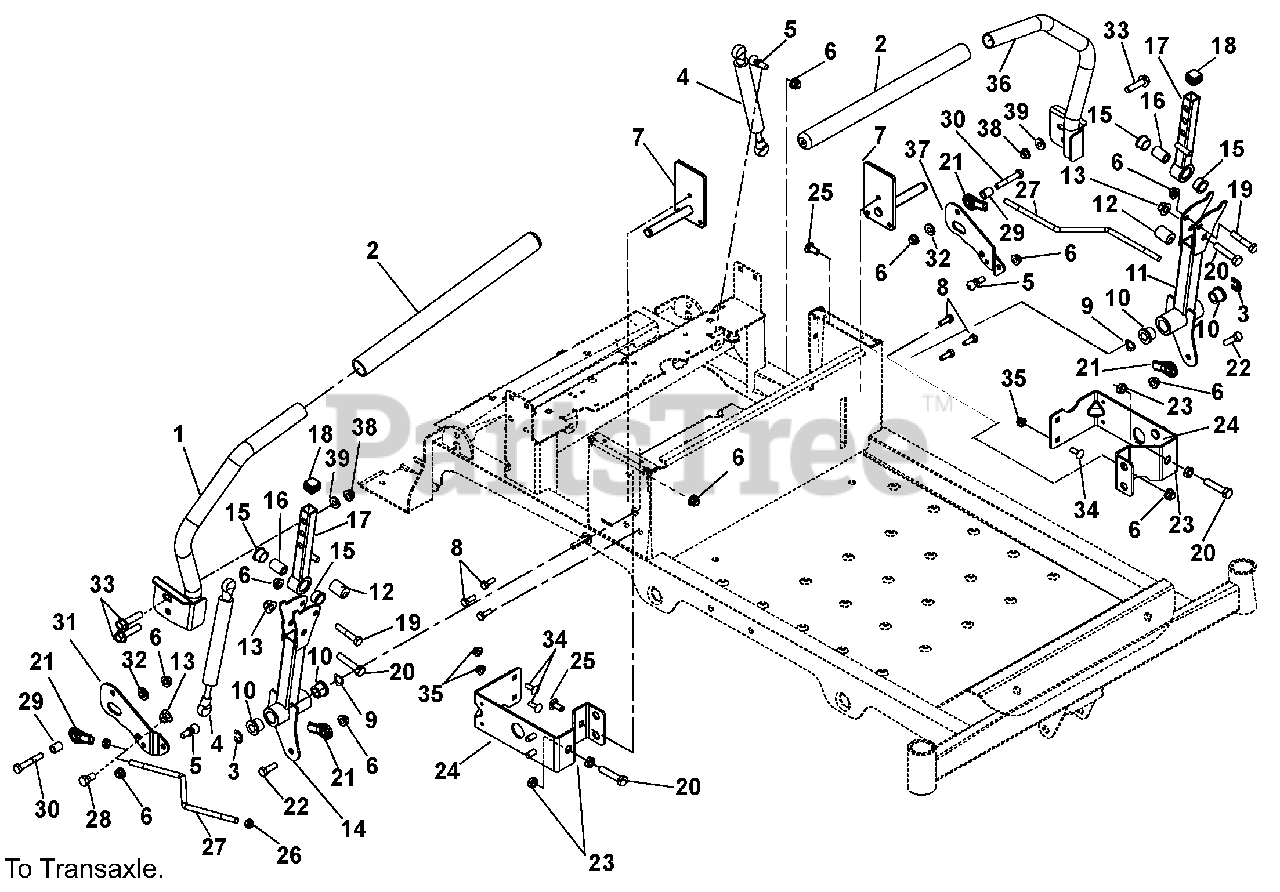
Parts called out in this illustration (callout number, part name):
1	Weldment, Steering Handle Right Hand
2	Grip, Handlebar 15" Foam
3	Ring, Retaining External .438 x 1.00 x 0.83
5	Stud, Ball
6	Nut, .31-18 Flange
7	Weldment, Steering Shaft
8	Screw, Tapping .25-20 x .50 Hex Washer Head
9	Washer, Wave
10	Bushing, Flanged
11	Weldment, Lower Control Arm
12	Bushing, Eccentric
13	Nut, .38-16 Nyloc Flange
14	Weldment, Lower Control Right Hand
15	Bushing, Flanged
16	Spacer, .375 x .625 x .970
17	Weldment, Upper Control Arm
18	Cap Plug, Square
19	Bolt, Hex .31-18 x 1.75
20	Bolt, Hex .375-16 x 1.75
21	Alignaball, 5/16 RH Thread
22	Bolt, Hex .31-18 x 1.00
23	Nut, Hex Jam .375-16
24	Bracket, Speed Adjustment/Seat Pivot
25	Bolt, Round Head Square Neck .31-18 x .75
26	Nut, Jam, .31-24
27	Wireform, Steering Link
28	Bolt, Hex .38-16 x .75
29	Spacer, .328 x .500 x .625
30	Bolt, Hex .31-18 x 2.00
31	Plate, Dampener Right Hand
32	Bushing, Flanged
33	Bolt, Serrated Hex Flange Washer Head .375-16 x 1.25
34	Bolt, Round Head Square Neck .25-20 x .75
35	Nut, Locking Nylon Flange .25-20
36	Weldment, Steering Handle Left Hand
37	Plate, Damper Left Hand
38	Nut, Locking Center Jam .375-16
39	Washer, Flat Steel .406 x .812 x .065
